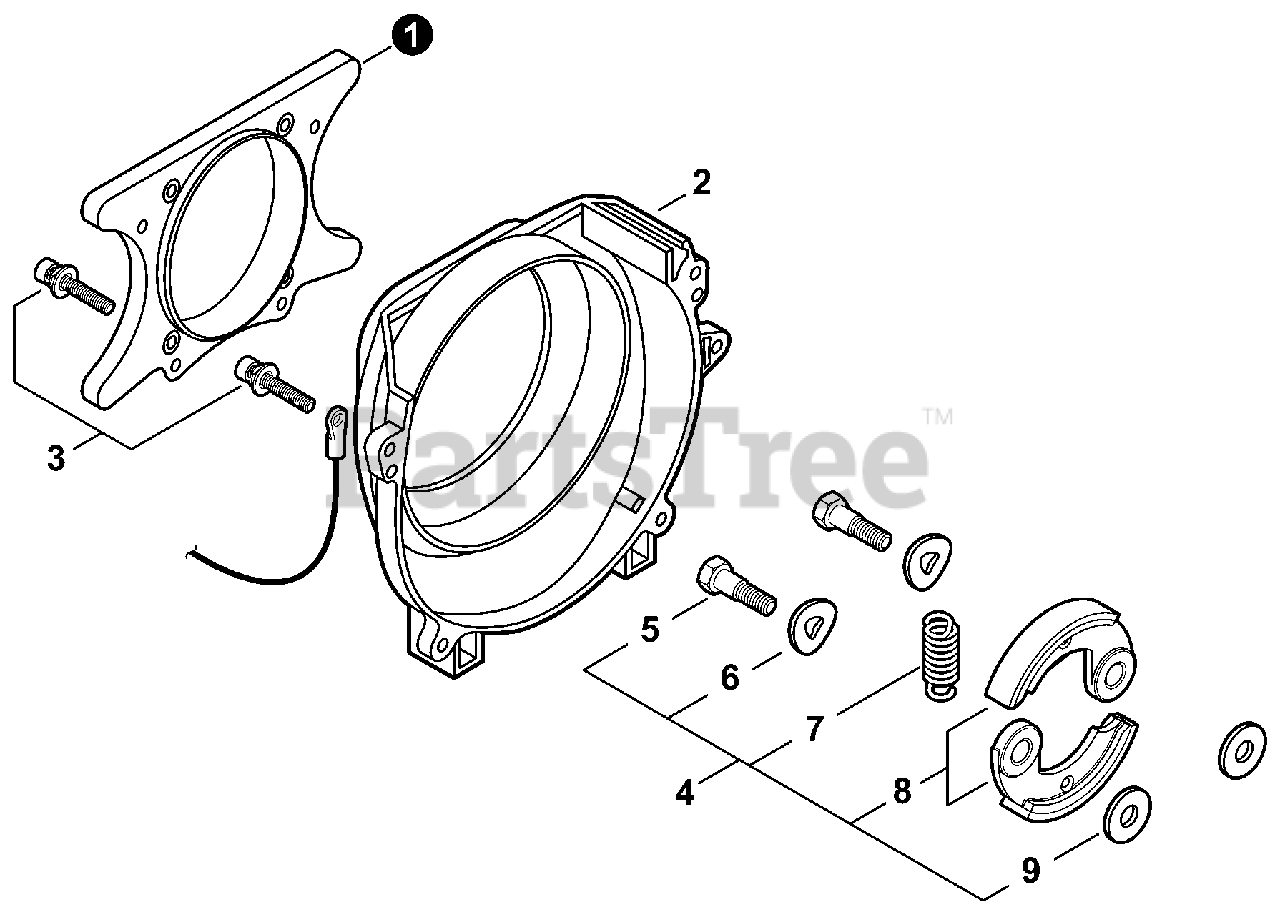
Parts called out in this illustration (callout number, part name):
1	PLATE, CLUTCH
2	COVER, FAN
3	BOLT 5×20
4	CLUTCH ASSY
5	BOLT, CLUTCH
6	WASHER, WAVE
7	SPRING, TENSION
8	SHOE, CLUTCH
9	WASHER 8.2×17×1.6
